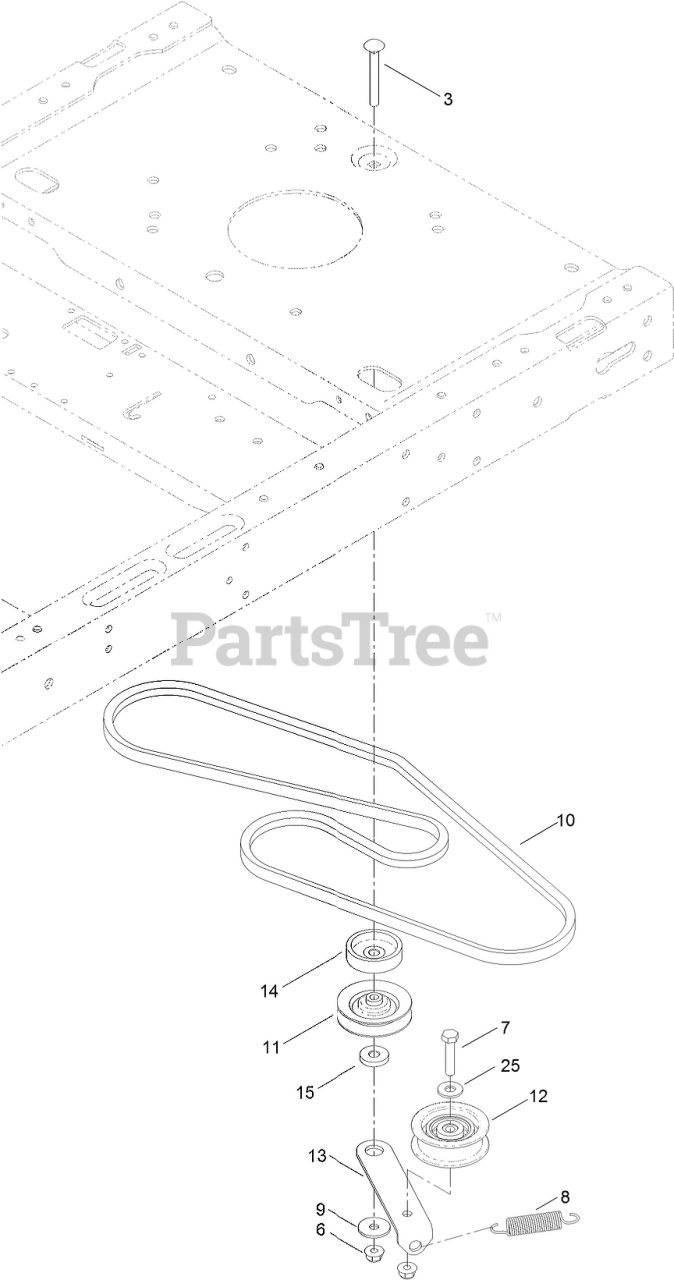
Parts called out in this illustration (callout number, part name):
3	SCREW-CARR
6	NUT-HF, NI
7	SCREW-HH
8	SPRING-RETURN, PEDAL
9	WASHER-PIVOT
10	V-BELT
11	PULLEY-IDLER
12	PULLEY-IDLER
13	ARM-IDLER
14	SPACER
15	SPACER-ARM, IDLER
25	WASHER-FLAT
